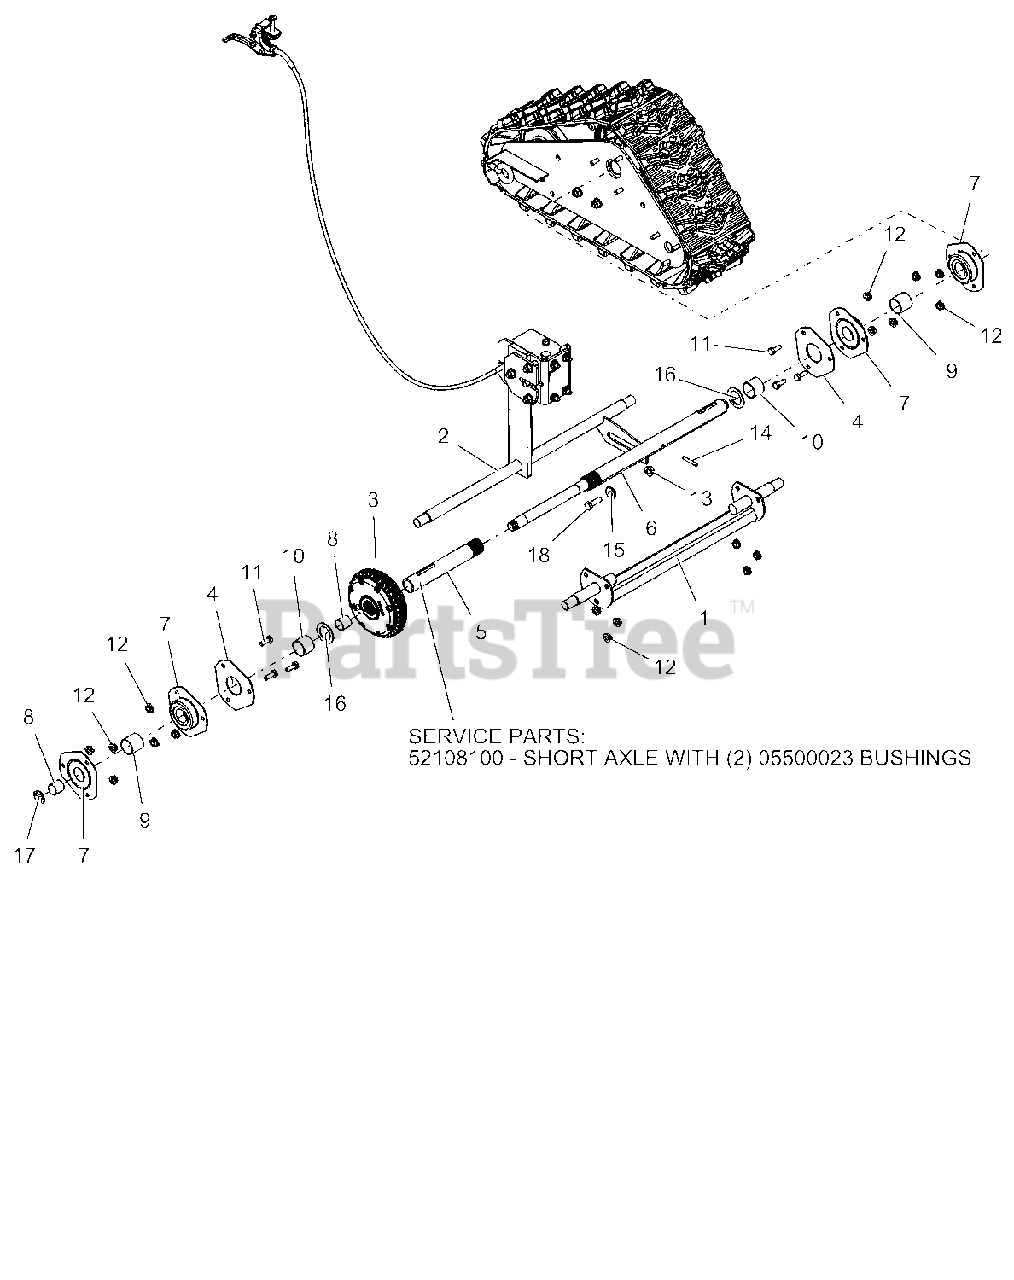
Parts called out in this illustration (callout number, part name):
1	AXLE, FRONT-DELUXE TRACK
2	AXLE, REAR - DELUXE TRACK
3	DIFFERENTIAL, AUTOMATIC
4	PLATE, BEARING SPACER
5	BSHG-SLV .706X.764X.75 BRZ
5	AXLE,SHORT - TRACK (DIFF)
5	AXLE,SHORT TRACK W/BUSHINGS
6	AXLE,LONG - TRACK (DIFF)
7	BRG-FLG 1.003/1.000 3 BOLT
8	BSHG-SLV .706X.764X.75 BRZ
9	BSHG-SLV, 1.012X1.125X1.00
10	BSHG-SLV, 1.012X1.125X.875
11	@BLT-HEX .25-20X.75 GR5 YWZC
12	@NUT-LK-CTR-FLG .25-20 YWZC
13	@NUT-LK-TOP-FLG .31-18 YWZC
14	PIN-ROLL .188X1.25
15	BSHG-FLG .325X.499X.3X.875
16	WSHR-FL-STL 1.010X1.505X.062YZ
17	RG-RTNG-EXT .625X.042
18	@BLT-HEX .31-18X1.00 GR5 YWZC
